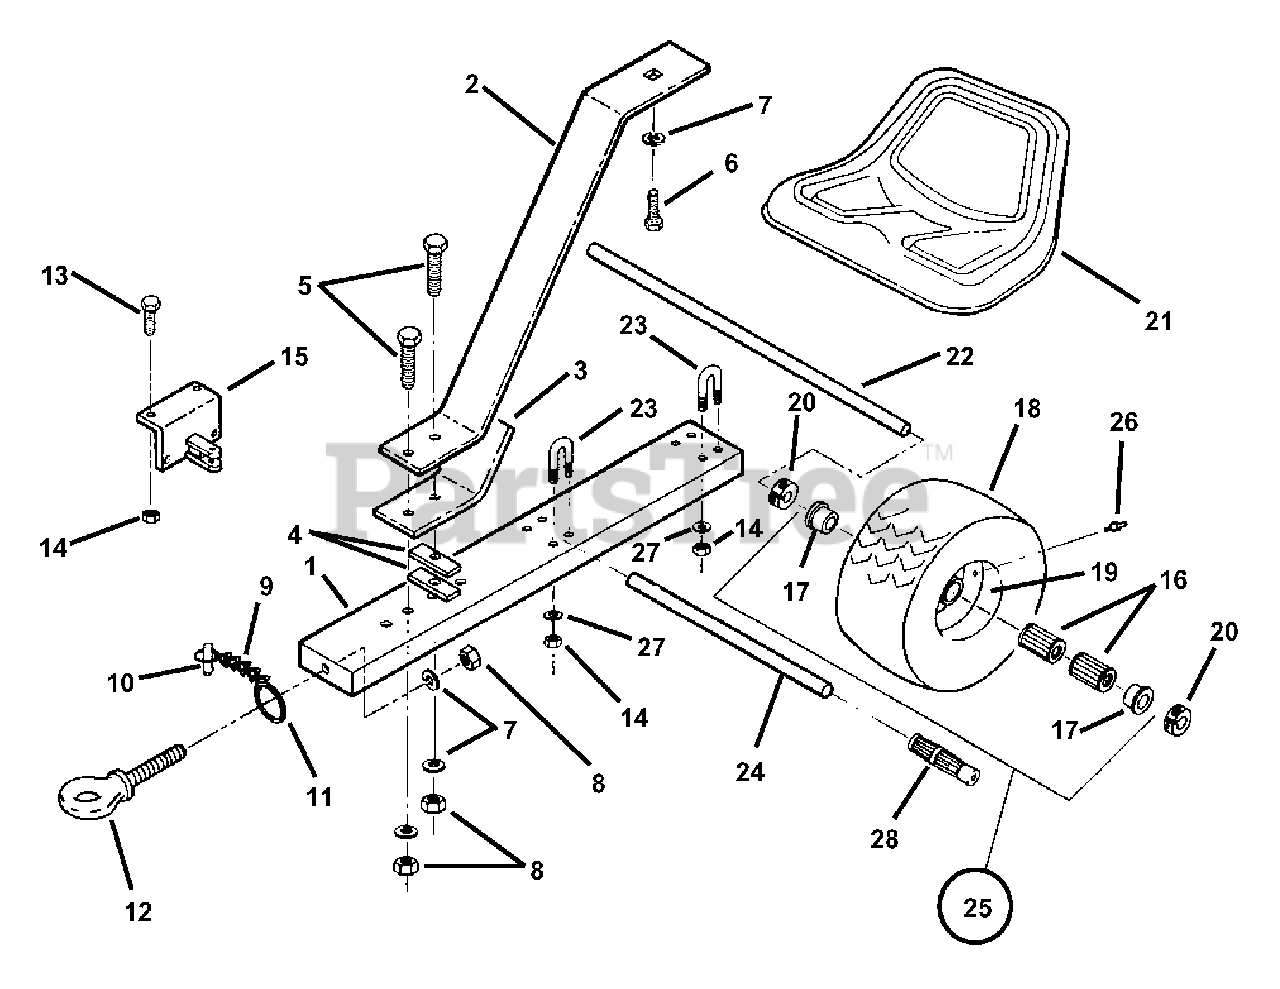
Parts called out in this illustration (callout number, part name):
1	FRAME (with decal)
3	STIFFENER
5	SCREW, 1/2-13 x 2" Hex
6	SCREW, 1/2-13 x 1" Hex
7	WASHER, 1/2" Split Lock
8	NUT, 1/2-13 Hex, Gr. 5 or B
9	CHAIN, #8 Sash (9" long)
10	PIN, Quick Release Hitch
11	SPLIT RING
12	EYEBOLT, 1/2" Dia. Forged
13	BOLT, 5/16-18 x 3/4" Hex
14	NUT, 5/16-18 Hex Nyloc (10)
15	HITCH
16	BEARING, Roller
17	BEARING, Flange
18	TIRE, 2 Ply Turfmaster
19	ASS'Y, Rim
20	CLAMP, Collar
21	SEAT w/Decal
23	U-Bolt (5/16-18 threads)
24	FOOT REST
25	ASS'Y, Tire
26	FITTING, 1/4-28 Grease
27	WASHER, 5/16" Flat
28	GRIP, Foot Rest
